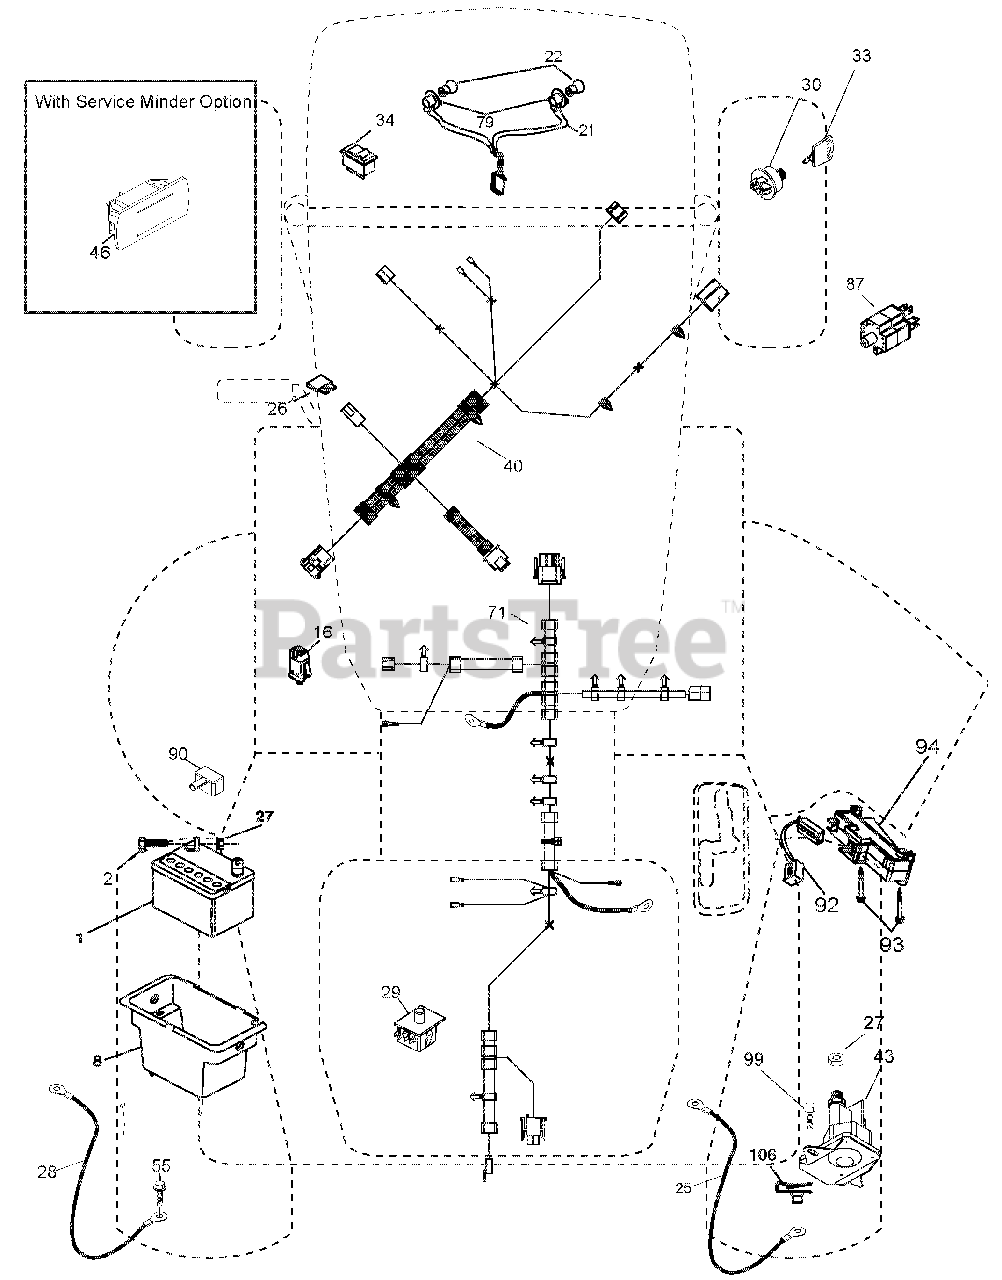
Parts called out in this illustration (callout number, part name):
1	BATTERY.12.VOLT.28.AMP.WET
2	BOLT.HEX.HD.1/4-20UNC X 3/4
8	BOX.BATTERY.MNT.REAR.LT.TEX.BL
16	SWITCH.INTERLOCK.NONO.GRAY
21	HARNESS ASM.LIGHT.22"(4152J)
22	BULB.LIGHT.#1156
25	CABLE STARTER 6 G4. BL/RED14.5
26	FUSE.20 AMP.
27	Nut, Keps Hex 1/4-20 unc
28	CABLE.BLACK.22"REAR BATT.TEX
29	SWITCH.SEAT.DELTA.OPC.9LB.
30	SWITCH.IGN.DLTA.P-IN.ROS
33	KEY/CHAIN.BLISTER PACK.GEN.USA
34	SWITCH.LIGHT/RESET.B/B/RED.
40	HARNESS IGN ELEC RELAY
43	SOLENOID.W/BRASS PLUNGER.2005
55	SCREW.5/16-18X3/4.SMGML.TAP/R
71	HARNESS.IGN.CHASSIS.TEX
79	SOCKET ASM.BULB.TWISTLOCK
87	SWITCH.INTRLCK.CLUTCH.CABLE.TX
90	COVER TERMINAL BATTERY FR. TEX
92	HARNESS.PIGTAIL.CONSLE.ROS.MLK
93	SCREW.PLASTITE.10-14 X 2.0
94	MODUAL REVERSE ROS
